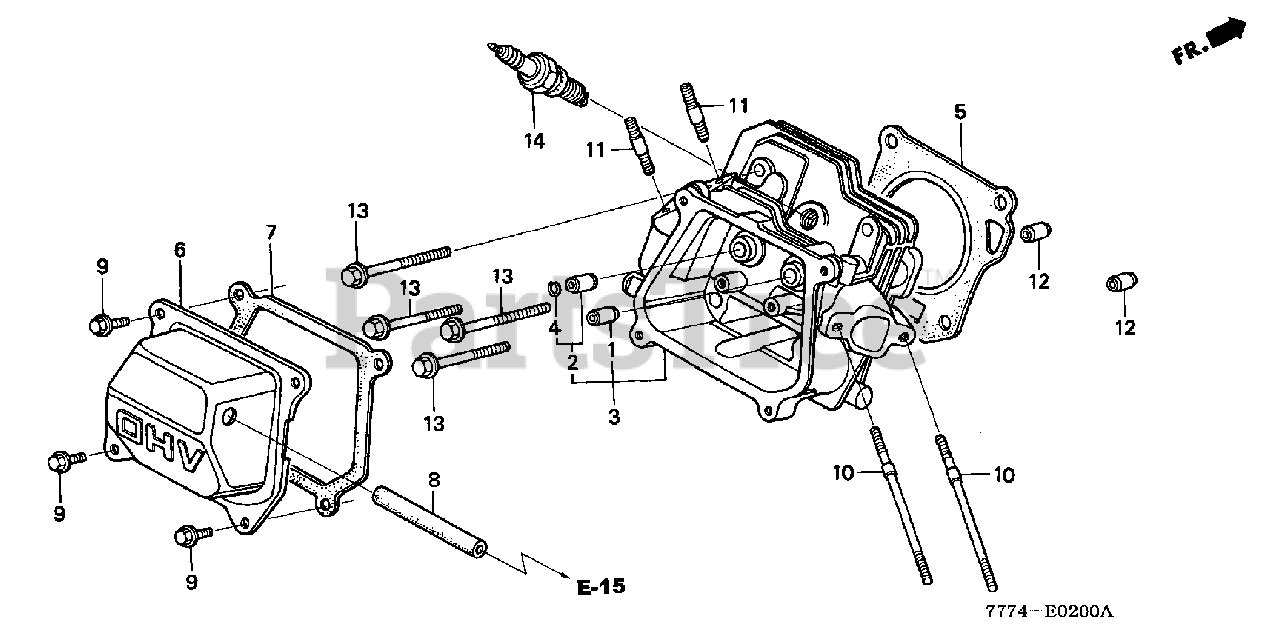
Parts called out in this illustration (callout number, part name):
1	GUIDE, VALVE (OS)
2	GUIDE, EX. VALVE (OS)
3	CYLINDER HEAD
4	CLIP, VALVE GUIDE
5	GASKET, CYLINDER HEAD
6	COVER, HEAD
7	GASKET, CYLINDER HEAD COVER
8	TUBE, BREATHER
9	BOLT, FLANGE (6X12) (CT200)
10	BOLT, STUD (6X109)
11	BOLT, STUD (8X32)
12	PIN, DOWEL (10X16)
13	BOLT, FLANGE (8X60)
14	SPARK PLUG (BPR5ES) (NGK)
14	SPARK PLUG (W16EPR-U) (DENSO)
14	SPARK PLUG (BPR6ES) (NGK)
14	SPARK PLUG (W20EPR-U) (DENSO)
